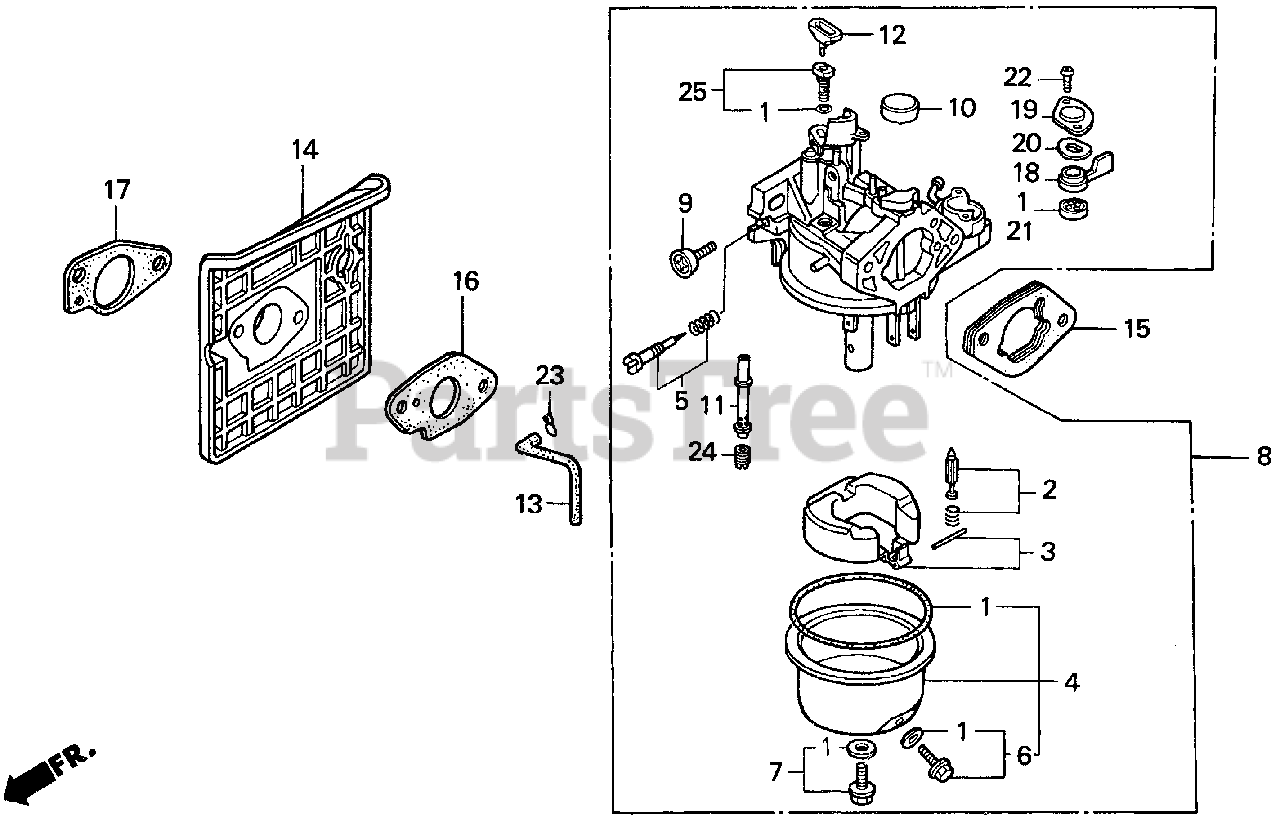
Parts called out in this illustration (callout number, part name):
1	GASKET SET
2	VALVE SET, FLOAT
3	FLOAT SET
4	CHAMBER SET, FLOAT
5	SCREW SET
6	SCREW SET, DRAIN
7	SCREW SET B
8	CARBURETOR ASSY. (SPEC)
9	SCREW, THROTTLE STOP
10	CAP, CHOKE LEVER DUST
11	NOZZLE, MAIN
12	COLLAR, SET
13	TUBE, AIR VENT (75MM)
14	INSULATOR, CARBURETOR
15	SPACER, CARBURETOR
16	GASKET, CARBURETOR
17	GASKET, INSULATOR
18	LEVER, VALVE
19	PLATE, LEVER SETTING
20	SPRING, VALVE LEVER
21	GASKET, VALVE
22	SCREW, PAN (3X6)
22	SCREW, PAN (3X8)
23	CLIP, TUBE (B8)
24	JET, MAIN (#85)
24	JET, MAIN (#88)
24	JET, MAIN (#90)
25	JET SET, PILOT (#38)
